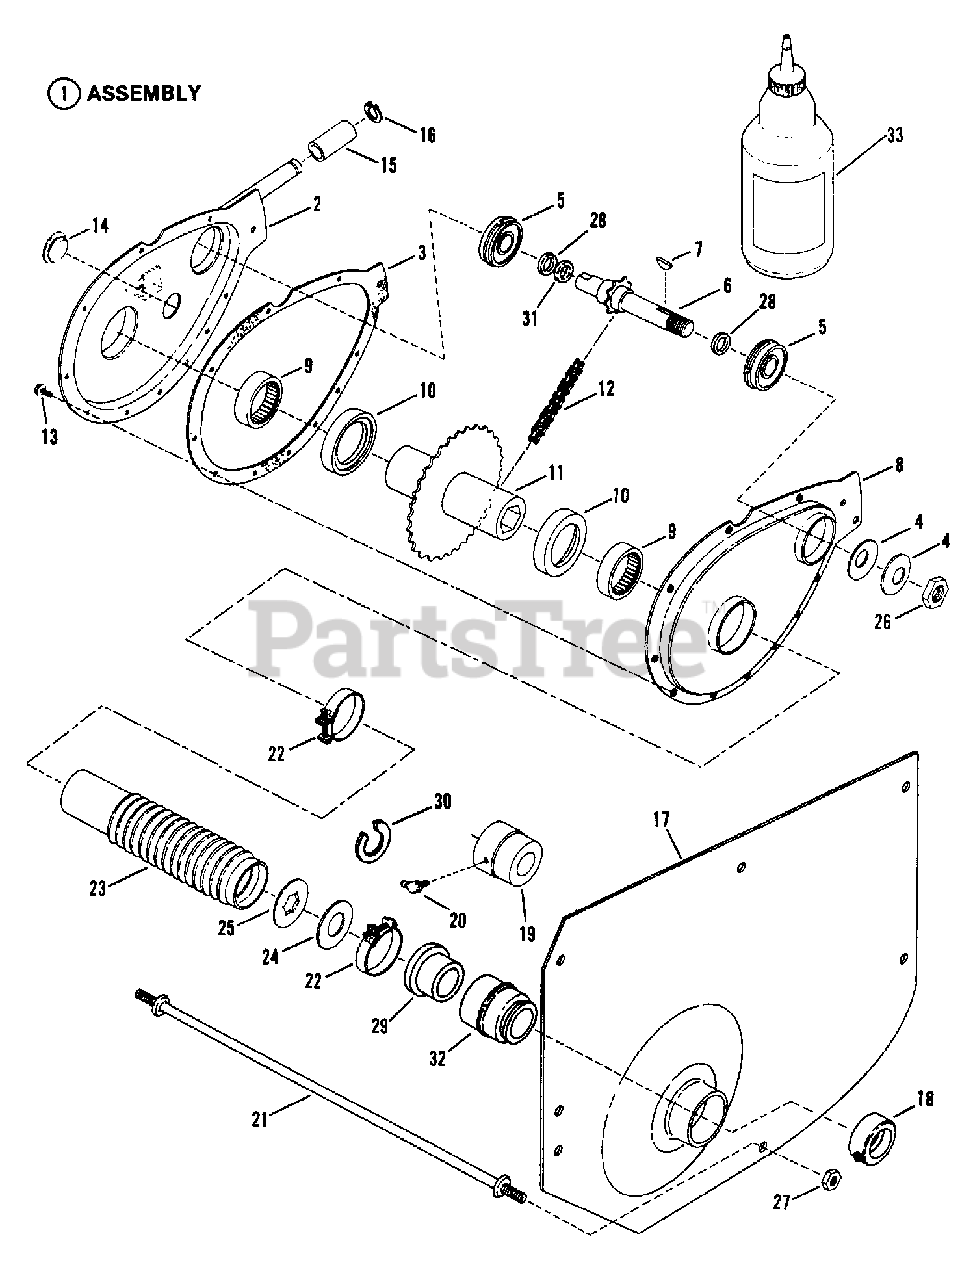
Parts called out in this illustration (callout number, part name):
1	ASSEMBLY, Chain Case
2	CASE, Sprocket
3	GASKET, Case Cover
4	WASHER, Belleville
5	BEARING, Ball
6	SPROCKET & SHAFT
7	KEY, 1/8 x 5/8" Woodruff
8	COVER, Chain Case
9	BEARING, Needle
10	WASHER, Nylon Thrust
11	HUB & SPROCKET
12	CHAIN
13	SCREW, #10-24 x 1/2" Hex Washer Self-Tap (Torx)
14	PLUG, Oil Fill & Check
15	ROLLER
16	RING, Retaining
17	FENDER, Left Hand
17	ASSEMBLY, Left Hand Fender
18	COLLAR, Lock
19	BEARING, Left Hand Fender
20	FITTING, Lube
21	ROD, Cross-Tie
22	CLAMP, Boot
23	BOOT, Oil Seal
24	WASHER, Thrust Nylon
25	WASHER, Thrust
26	NUT, 5/8-18 Hex Lock
27	NUT, 5/16-24 Hex Flange Lock
28	O-RING
29	SPACER
30	WASHER, Shim
31	WASHER, Shim
32	BEARING, Left Hand Fender
32	Bearing
33	GREASE
